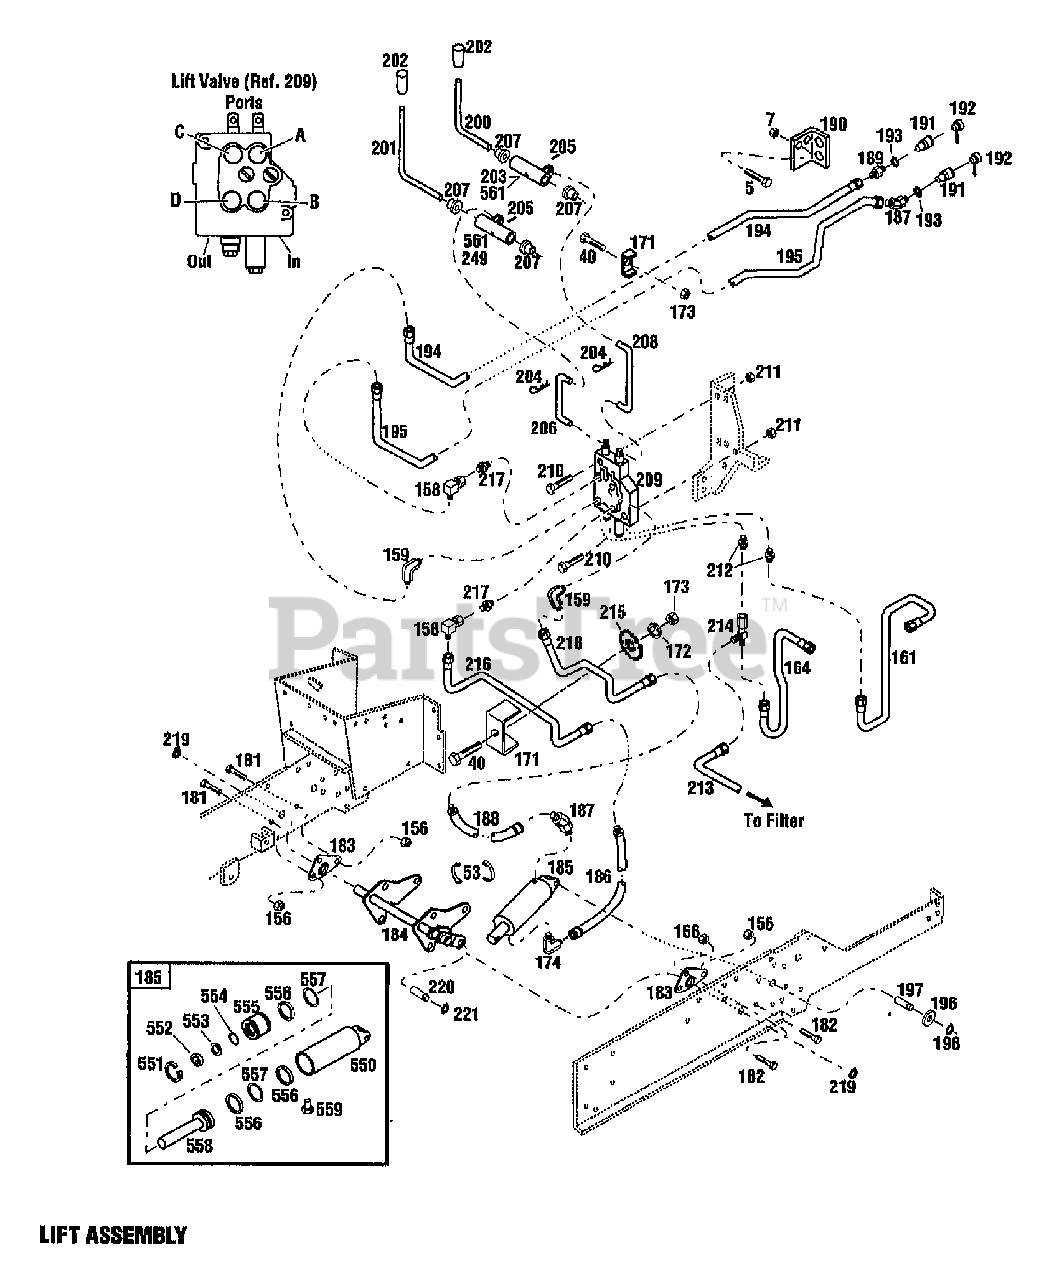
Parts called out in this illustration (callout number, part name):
5	SCR-HFLK 3/8-16X1.00 ZP
7	NUT-HFLK 3/8-16 ZP
40	SCR-HH 5/16-18X1.0 G5 ZP
53	TIE-CABLE NYLON BLACK
156	NUT-HFLK 5/16-18 ZP
158	CONNECTOR
159	ELBOW
161	TUBE-HYD PB VALVE
164	TUBE-HYD S C U TANK
171	CLAMP
172	WASHER-LK .312 ZP
173	NUT-HEX 5/16-18 ZP
174	ELBOW
181	SCR-LOCK
182	SCR-LOCK
183	BEARING-LIFT SHAFT
185	ASSM-CYL HYDRAULIC
187	ELBOW
188	ASSM-HOSE
189	CONNECTOR
190	BRKT-COUPLING
191	COUPLING-BODY
192	PLUG-DUST
193	RING-RET. EXT .875 ID
194	TUBE-HYD AUX-OUT
195	TUBE-HYD AUX-IN
196	WASHER-1.5X.755X.062
198	RING-RETAIN EXT .707 ID
200	LEVER-CONTROL
201	LEVER-CONTROL
202	KNOB-SHIFT LEVER
203	ARM-CONTROL
204	PIN-CLIP .08
205	PIN-DRIVE
206	LINK-VALVE
207	BRG-FLANGE
208	LINK-VALVE
209	VALVE-HYDRAULIC
210	SCR-HFLK 1/4-20X2.00 G5ZP
211	NUT-HF/LK 1/4-20 ZP
212	CONNECTOR
213	TUBE-HYD RETURN
214	TEE-SWIVEL
215	WASHER-FLAT 1.25X.406X.179
216	TUBE-HYD VALVE TO ROD
217	ELBOW
218	TUBE-HYD VALVE TO HEAD
219	RING-RETAINING
221	RING-RETAIN .625 ID
249	ASSM-CONTROL ARM
550	ASSM-CYL HYDRAULIC
551	RING-RETAIN INT 2.210 DIA
552	SEAL-OIL
553	RING-BACK/UP
554	RING-O .984 ID
555	HEAD-CYLINDER
556	RING-BACK/UP
557	RING-O 1.6 ID
558	ASSM-ROD HYDR CYLINDER
559	PLUG-PIPE
561	ARM-CONTROL
